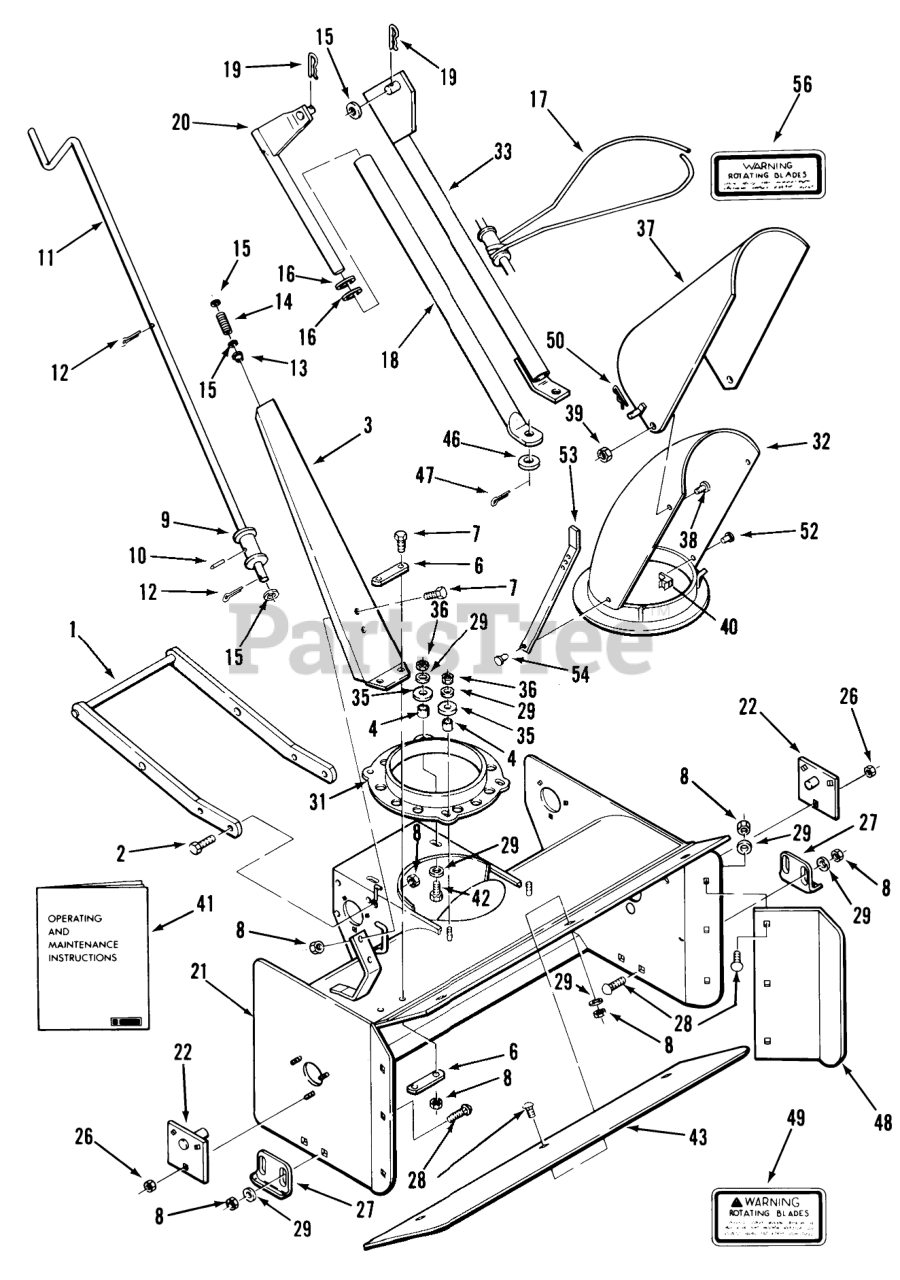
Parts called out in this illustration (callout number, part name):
1	Frame-Mounting
2	Bolt
3	Crank Support
4	SPACER
6	Bar-Reinforcing
7	Bolt
8	Nut
9	ASSY TUBE CRANK R
10	ROLL PIN 1/4 X 1-1/4
11	CRANK R
12	Pop Rivet
13	NYLINER BUSHING
14	SPRING-COMPRESSION
15	Washer
16	Washer
17	CABLE
18	ASSY LIFT TUBE R
19	Hairpin Cotter
20	Lid Rod
21	Wrapper Assembly
22	Plate
26	Nut
27	Skid
28	Bolt
29	Washer
31	COLLAR
32	S/A SHROUD R
33	ASSY LIFT TUBE
35	WASHER
36	NUT
37	Deflector
38	MACH. SCREW
39	Nut
40	CLAMP
41	Operating and Maintenance Instructions
42	Bolt
43	Plate
46	WASHER
47	Cotter Pin
48	Plate
49	DECAL-WARNING
50	Hairpin
52	RIVET-4
53	ARM R
54	RIVET
56	DECAL-WARNING
